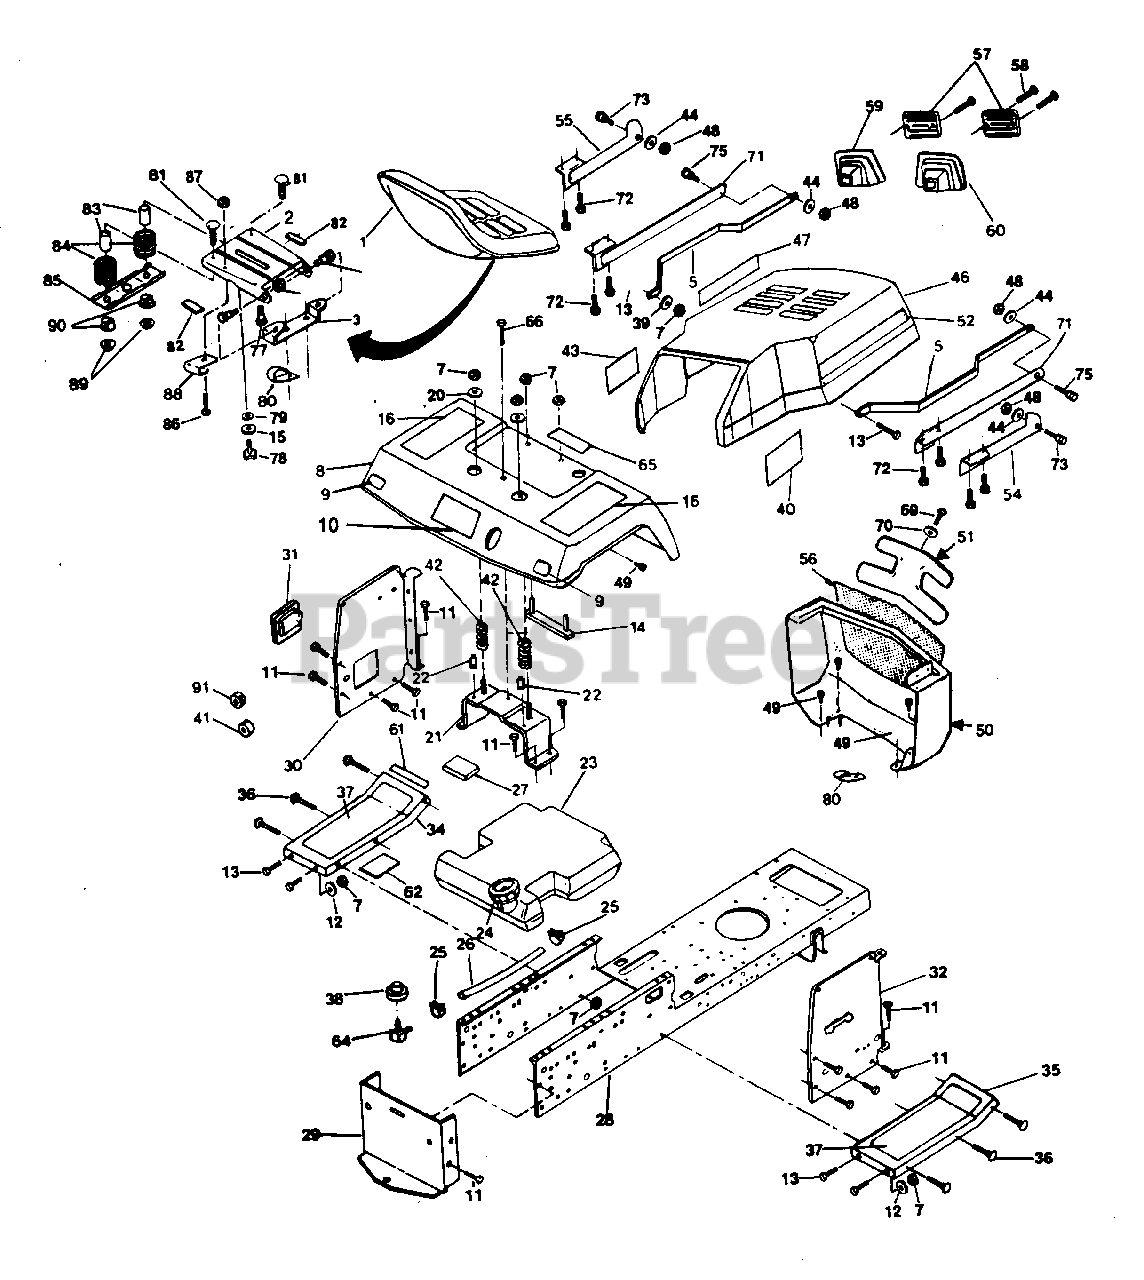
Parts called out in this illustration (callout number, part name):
1	Seat (AYP part number)
2	Seat Pan (AYP part number)
3	Seat Pivot Bracket (AYP part number)
4	Shoulder Bolt (AYP part number)
5	Grill Brace (AYP part number)
6	Locknut
7	Locknut
8	Fender (AYP part number)
9	Rear Reflector (AYP part number)
10	Poulan Decal (AYP part number)
11	Thread Roll Washer Hex Screw (AYP part number)
12	Washer (AYP part number)
13	Hex Bolt 3/8-16 x 3/4 (AYP part number)
14	Fender Strap (AYP part number)
15	Washer (AYP part number)
16	6-speed Decal (AYP part number)
20	Washer (AYP part number)
21	Fender Bracket (AYP part number)
22	Push Nut (AYP part number)
23	Fuel Tank (AYP part number)
24	Fuel Cap (AYP part number)
25	Hose Clamp (AYP part number)
26	Fuel Line (AYP part number)
27	Spacer Pad (AYP part number)
28	Chassis Assembly (AYP part number)
29	Drawbar (AYP part number)
30	L.H. Dash Panel (AYP part number)
31	Access Cover (AYP part number)
32	R.H. Dash Panel (AYP part number)
34	L.H. Footrest (AYP part number)
35	R.H.Footrest (AYP part number)
36	Carriage Bolt (AYP part number)
37	Footrest Pad (AYP part number)
38	Bushing (Dana part number) (AYP part number)
39	Washer 13/32 x 7/8 x 16 Ga. (AYP part number)
40	R.H. 14HP Decal
41	Grommet (AYP part number)
42	Compression Seat Spring (AYP part number)
43	L.H. 14HP Decal (AYP part number)
44	Washer (AYP part number)
46	Hood (AYP part number)
47	L.H.Hood Decal (AYP part number)
48	Crownlock Nut (AYP part number)
49	Thread Roll Washer Hex Screw (AYP part number)
51	Grill Insert
52	R.H. Hood Decal (AYP part number)
54	R.H. Hinge Strap Assembly (AYP part number)
55	L.H. Hinge Strap Assembly (AYP part number)
56	Grill Screen (AYP part number)
57	Lens (AYP part number)
58	Pan Head Cross Screw (AYP part number)
59	L.H. Bezel (AYP part number)
60	R.H. Bezel (AYP part number)
61	Clutch/Brake Decal (AYP part number)
62	Drive Belt Decal (AYP part number)
64	Fuel Tank Stem (AYP part number)
65	Caution Decal (AYP part number)
66	Thread Roll Washer Hex Screw (AYP part number)
69	Slotted Hex Screw (AYP part number)
70	Washer (AYP part number)
71	Rear Hinge Strap Assembly (AYP part number)
72	Washer Head Hex Screw (AYP part number)
73	Shoulder Bolt (AYP part number)
75	Shoulder Bolt (AYP part number)
77	Shoulder Bolt (AYP part number)
78	Seat Knob 1/2 (AYP part number)
79	Lock Washer 1/2 (AYP part number)
80	Fuel Line Clip (AYP part number)
81	Carriage Bolt (AYP part number)
82	Foam Strips (AYP part number)
83	Spacer (AYP part number)
84	Compression Spring (AYP part number)
85	Bracket Switch (AYP part number)
86	Pan Hd. Slotted Screw (AYP part number)
87	Keps Nut (AYP part number)
88	Insulated Clip (AYP part number)
89	Flanged Locknut (AYP part number)
90	Snap Bushing (AYP part number)
91	Split Grommet (AYP part number)
